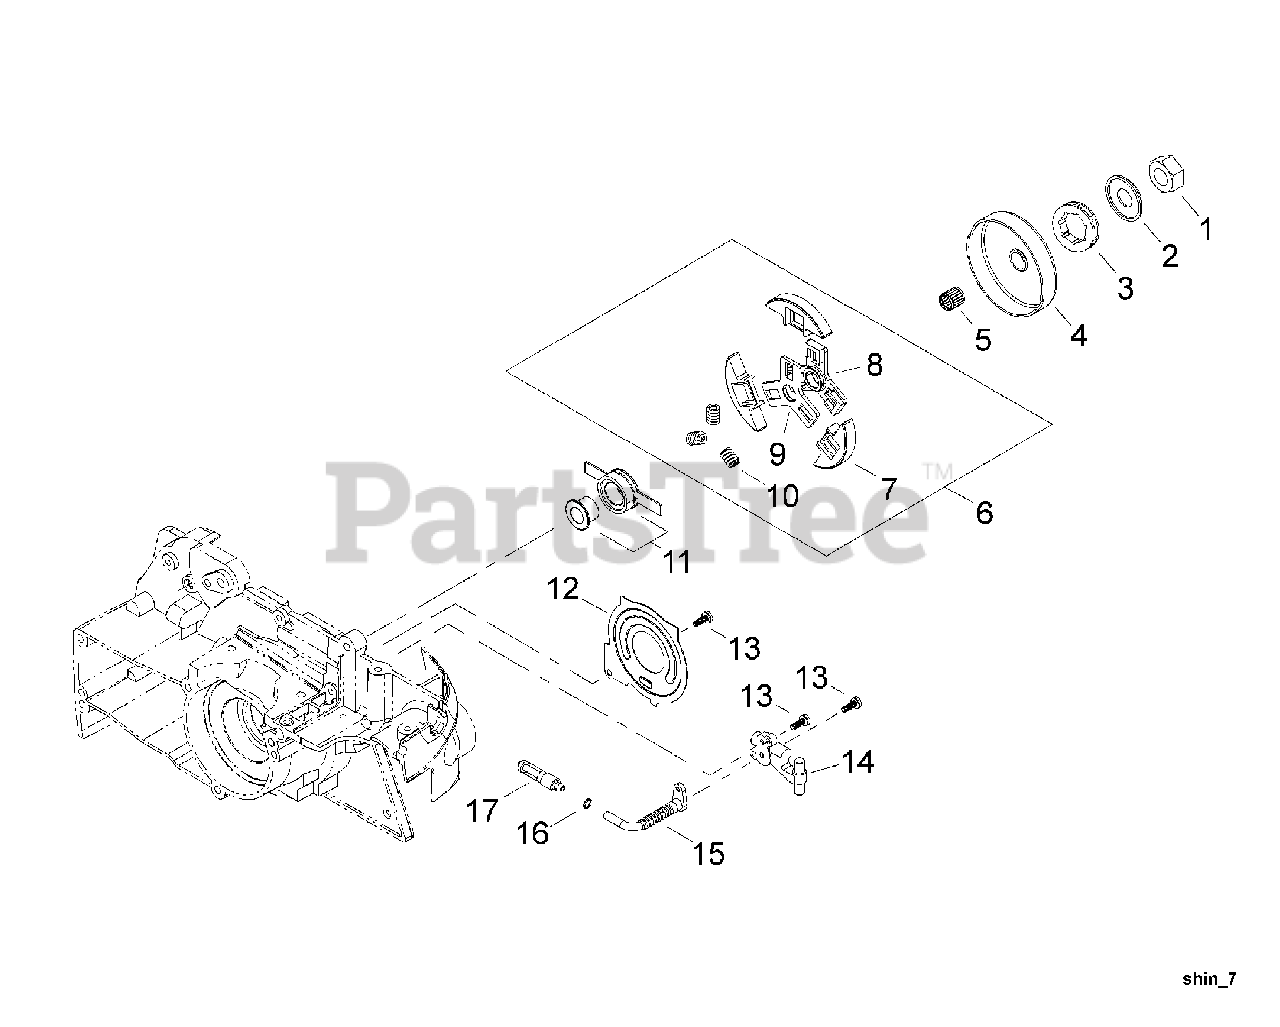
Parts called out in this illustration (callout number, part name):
1	NUT - 10
2	COLLAR
3	SPROCKET, RIM
4	DRUM, CLUTCH
5	BEARING, NEEDLE
6	CLUTCH ASSY
7	SHOE, CLUTCH
8	HUB, CLUTCH - OUTER
9	HUB, CLUTCH - INNER
10	SPRING, CLUTCH
11	GEAR ASSY
12	COVER, PUMP
13	SCREW - 4X14
14	AUTO-OILER ASSY
15	PIPE - OIL
16	RING, RETAINING - 6
17	FILTER, OIL
